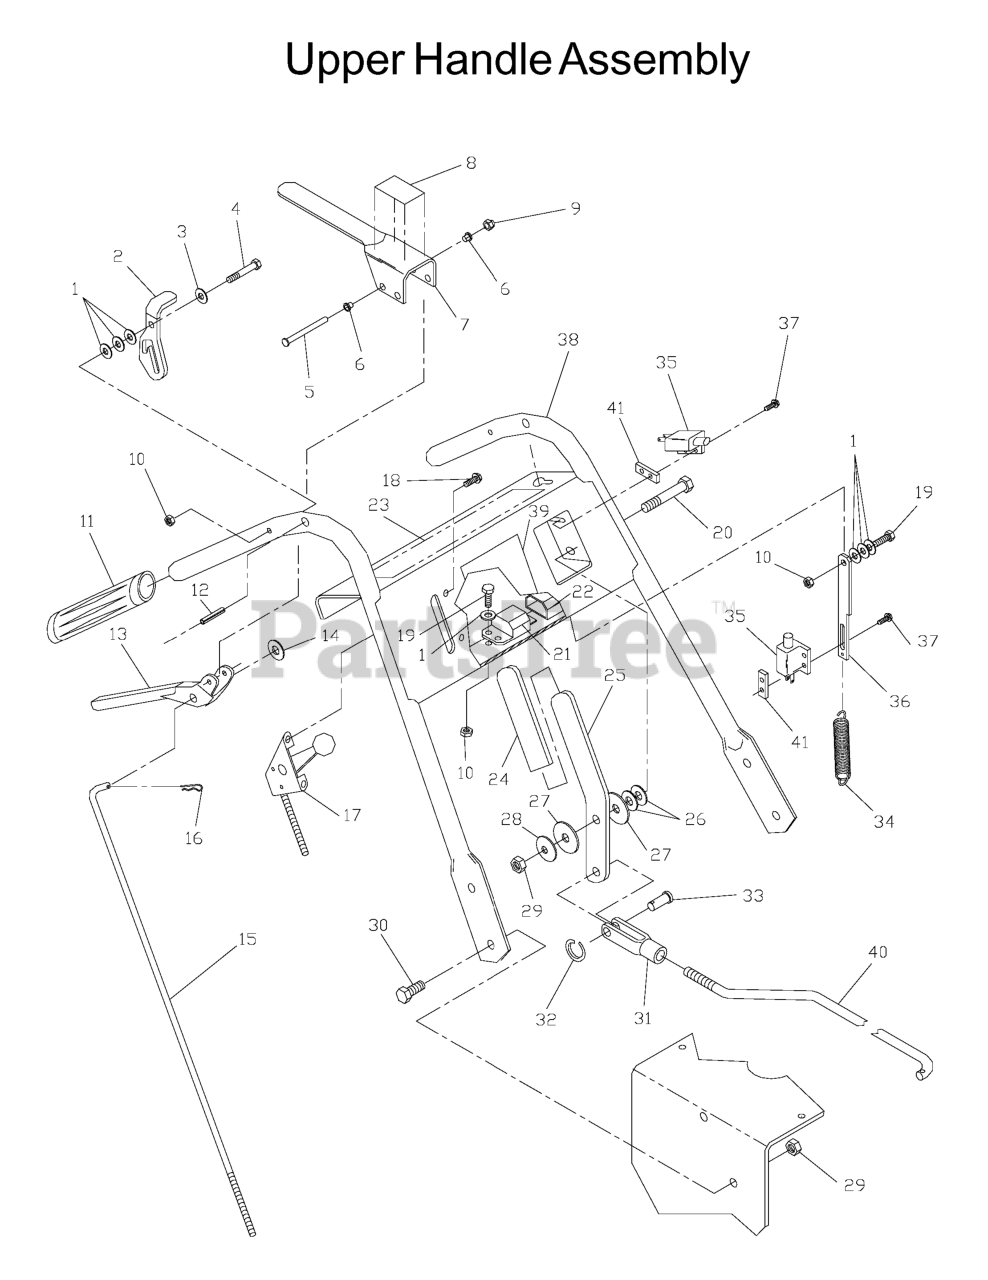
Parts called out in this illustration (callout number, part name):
1	WASHER 1/4 SAE
2	LATCH LT THUMB W/GRIP
3	WASHER, WAVE SPRING
4	BOLT 1/4C X 1 3/4
5	PIN CLEVIS
7	LEVER OPC W/GRIP
8	DECAL, THUMB LATCH
10	NUT 1/4C CENTER LOCK
11	GRIP HANDLE
12	ROLL PIN 5/16 X 1.125
13	LEVER, MOLDED DRIVE
14	WASHER 5/16 FLAT
15	TRACTION ROD
16	HAIRPIN #2
17	THROTTLE CONTROL W/BALL KNOB
18	HWST 1/4C X 3/8
19	HCS 1/4C X 3/4 HCS
20	HCS 3/8C X 1 1/2
22	HANDLE HARNESS, KAW
23	DECAL, OPERATING
26	WASHER 3/8 FLAT
27	WASHER, FIBER
28	CONE WASHER
29	NUT 3/8C CENTERBLOCK
30	HCS 3/8-16X1.GRD.5.ZD
31	YOKE-3/8-24 PLTD
33	CLEVIS PIN 3/8 X 1 1/8
36	LINKAGE, O P
37	SCREW #10-24 X 5/8
38	HANDLE, UPPER W/DECALS
39	DECAL, OPERATION
41	TAPPED PLATE
539976388	LATCH, RT.THUMB W/GRIP
